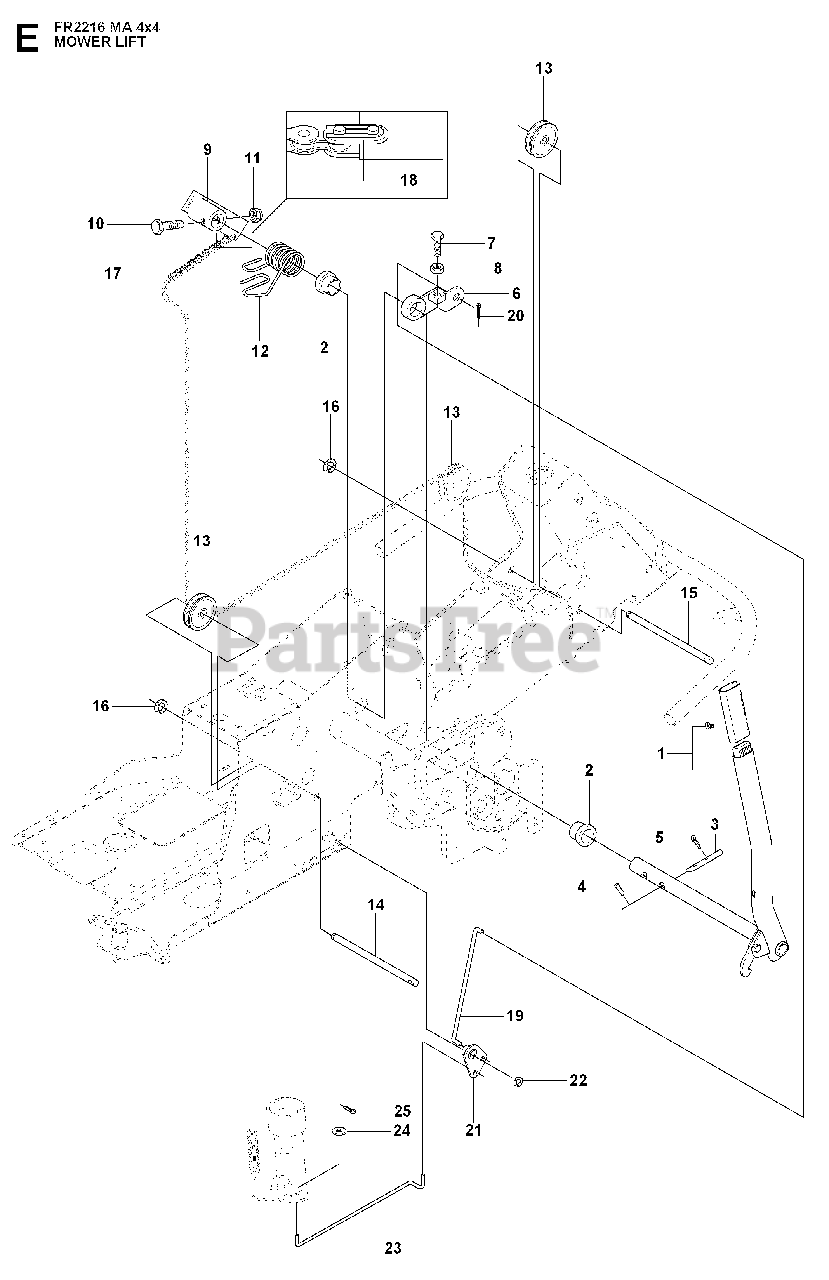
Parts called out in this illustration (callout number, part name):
1	LIFTING LEVER ASSY
2	BUSH
3	RP PIN
5	SPLIT PIN
6	LEVER CLUTCH
9	LIFTING ARM
16	LOCK RING
19	CONNECTION ROD
20	SPLIT PIN
22	RETAINING RING
23	CONNECTION ROD
25	SPLIT PIN
